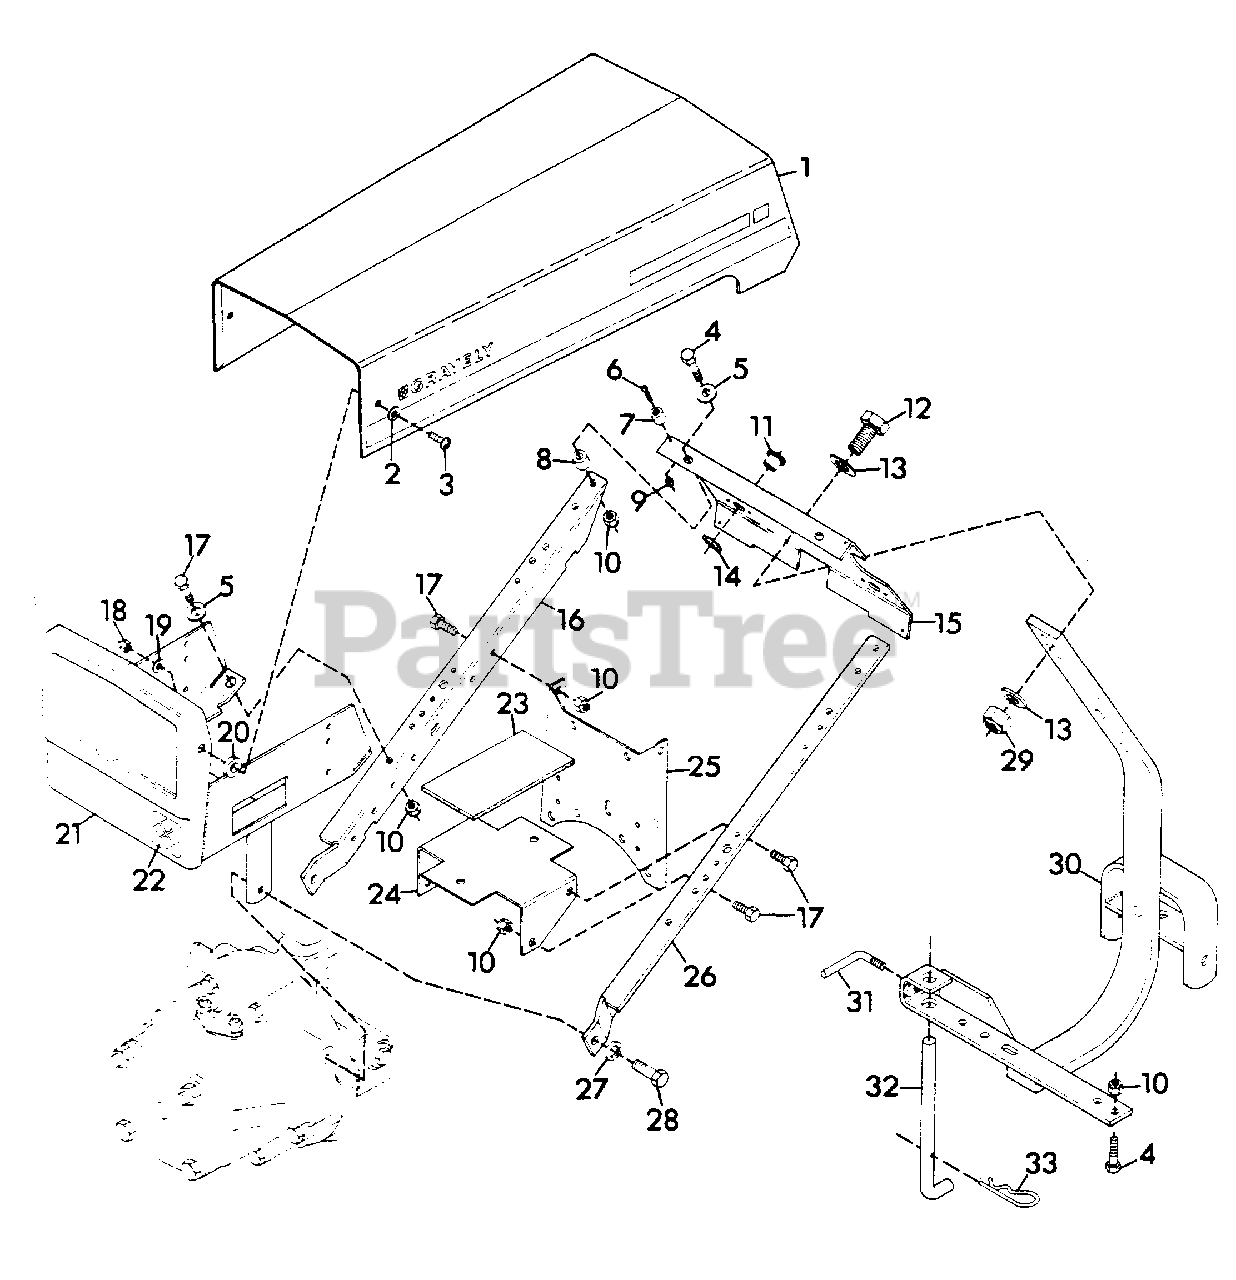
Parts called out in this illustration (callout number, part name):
1	ASSEMBLY, HOOD
2	WASHER, FLAT .281X.625X.065
3	SCREW, MACH. 1/4-20X1.00 PHD
4	BOLT, HEX 3/8-16X1.50
5	WASHER, FLAT .406X.812X.065
6	SCREW, MACH. 6-32X.625 PHD
7	BUMPER
8	BUSHING, REVERSE IDLER
9	NUT, MACH. LOCK 6-32
10	NUT, LOCK 3/8-16
11	BUSHING, .513X.750X.625
12	BOLT, HEX 5/8-11X2.00
13	WASHER, FLAT .656X1.250X.100
14	RING, RETAINING
15	PLATE, SILK SCREEN
16	SUPPORT, HANDLEBAR R.H.
17	BOLT, HEX 3/8-16X.875
18	NUT, LOCK 1/4-20
19	WASHER, FLAT .313X.875X.065
20	BUSHING, HOOD
21	WELDMENT, BATTERY BRACKET
22	DECAL
23	PAD, GAS TANK
24	BRACKET, TANK SUPPORT
25	BRACKET
26	SUPPORT, HANDLEBAR L.H.
27	WASHER, LOCK 1/2 REG.
28	BOLT, HEX 1/2-13X1.00
29	NUT, LOCK 5/8-11
30	WELDMENT, HITCH 10 AND 12 H.P.
31	HANDLE, ADJUSTING
32	STAND, KICK
33	PIN, HAIR
NS	DECAL, 10
NS	DECAL, 12
NS	DECAL, 16
NS	DECAL, SIDE STRIPE
NS	DECAL, GRAVELY LOGO
NS	DECAL, 6 LEAD
NS	DECAL, 8 LEAD
NS	DECAL, PROFESSIONAL
